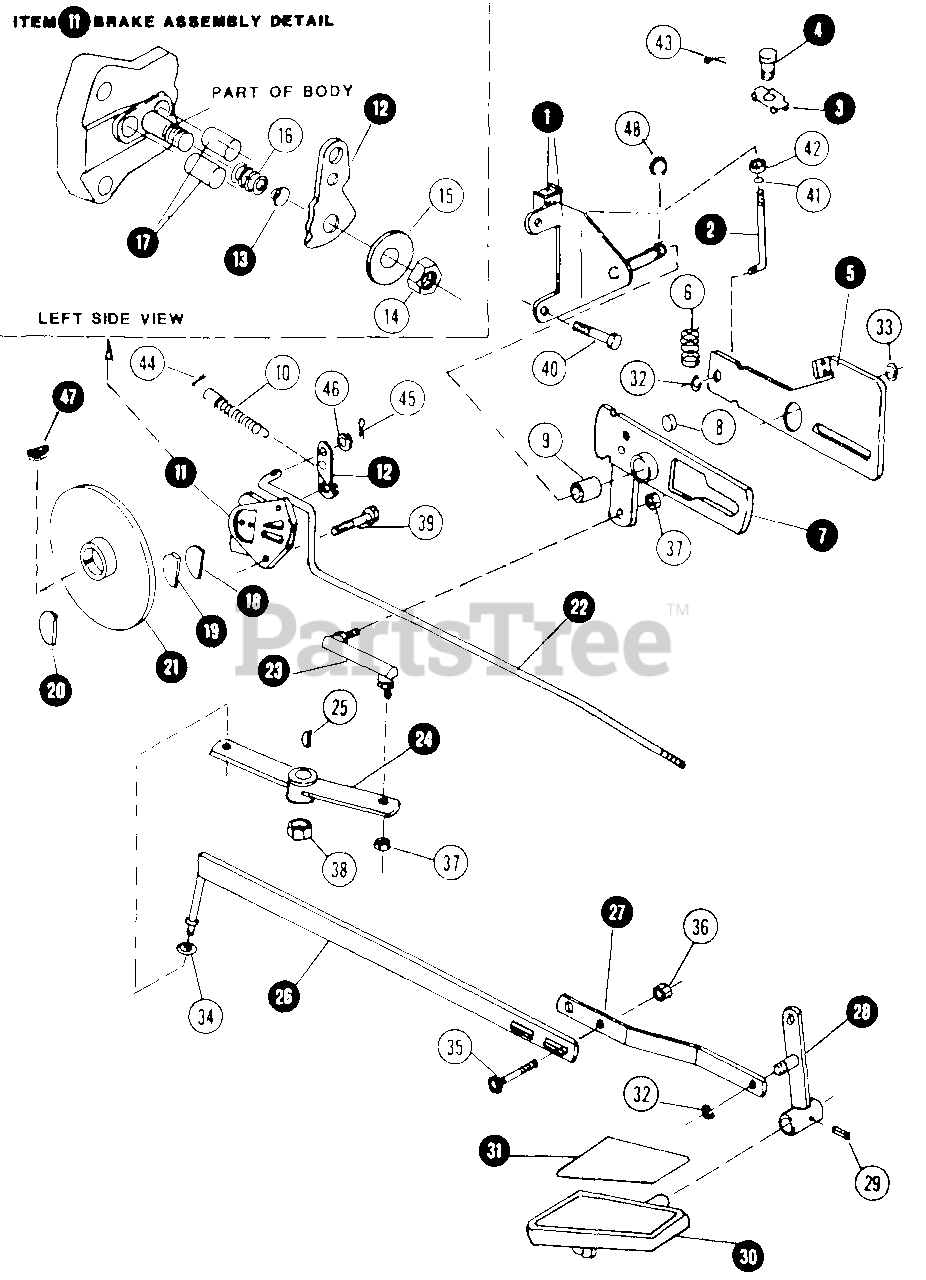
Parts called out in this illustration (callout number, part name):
1	BRACKET, TRUNNION MOUNTING
2	LINK, NEUTRAL ADJUSTING
3	RETAINER, ADJUSTING LINK
4	STUD, ADJUSTING
5	GUIDE, ROLLER
6	SPRING, NEUTRAL RETURN
7	CAM, NEUTRAL RETURN - ASSEMBLY
8	PLUG, FRICTION
9	BEARING
10	SPRING, BRAKE RETURN
11	BRAKE ASSEMBLY
13	FERRULE
14	NUT, CAM RETAINING
15	WASHER THRUST
16	SPRING, PUSH PIN
17	PIN, PUSH
18	DISC, PAD BACK-UP
19	PAD, FRICTION
20	PAD, FRICTION
21	DISC ASSEMBLY
22	ROD, AXLE BRAKE
23	LINK, TRANSMISSION LEVER
24	LEVER, DIRECTIONAL CONTROL
25	KEY, WOODRUFF
26	LINK, REAR CONTROL
27	LINK, FRONT CONTROL
28	LEVER, PEDAL PIVOT
29	PIN, GROOVE 1/4 x 1.25"
30	PEDAL, DIRECTIONAL CONTROL
31	TREAD, CONTROL PEDAL
32	RING, RETAINING
33	RING, RETAINING
34	RING, RETAINING
35	BOLT 1/4NF x 3/4 CARRIAGE
36	NUT, 1/4NF HEX
37	NUT, 3/8C HEX
38	NUT, 1/2C HEX
39	BOLT, 3/8C x 1-1/4 HEX
40	SCREW, HEX HEAD CAP 3/8-16 x 3 GR.5
41	RING, RETAINING
42	RING, ADJUSTING STUD
43	COTTER-PIN, 1/16 x 1"
44	COTTER-PIN, 5/16-1"
45	COTTER-PIN, 3/32 x 1/2"
46	WASHER, 1/4 FLAT
47	KEY, WOODRUFF
48	RING, RETAINING
